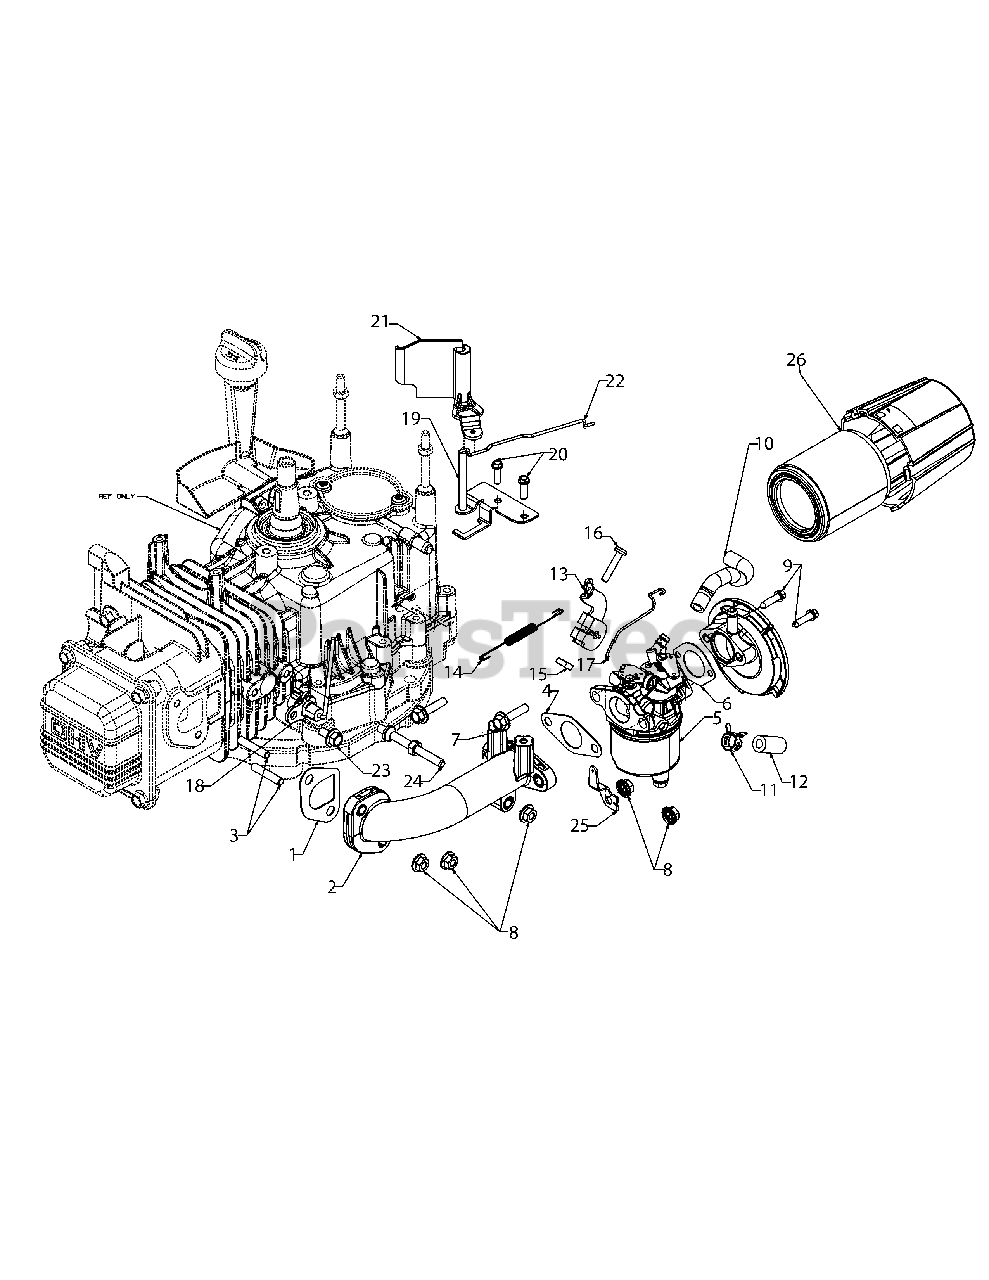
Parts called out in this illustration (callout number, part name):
1	Gasket-Manifold 19
2	Manifold Asm-Intk
3	Hhflg-M6-1:20:CL5.8
4	Gasket-Manifold Ca
5	Carb Asm-Choke 195
5	Carb Kit-Svc 195
6	Gasket-Carb 195
7	Hhflg-M6-1:25 Cl5.
8	Nut-Hex Flange M6-
9	Screw-Machine M5-8
10	Tube-Breather
11	Clamp-Hose 12Mm
12	Hose:Fuel Low Perm
13	Bracket-Governor C
14	Spring-Extension .
15	Nut-Sq M5-0.8
16	Screw-Machine M5-8
17	Rod-Throttle Contr
18	Rod Asm-Choke Over
19	Bracket-Support Ai
20	Screw-M5-2.2:16 Pl
21	Vane-Choke 195
22	Rod-Choke Control
23	Hhflg-M6-1:12 Cl8.
24	Stud-M6-1:30.5 Lg
25	Bracket-Governor S
26	Filter Asm-Air Cle
